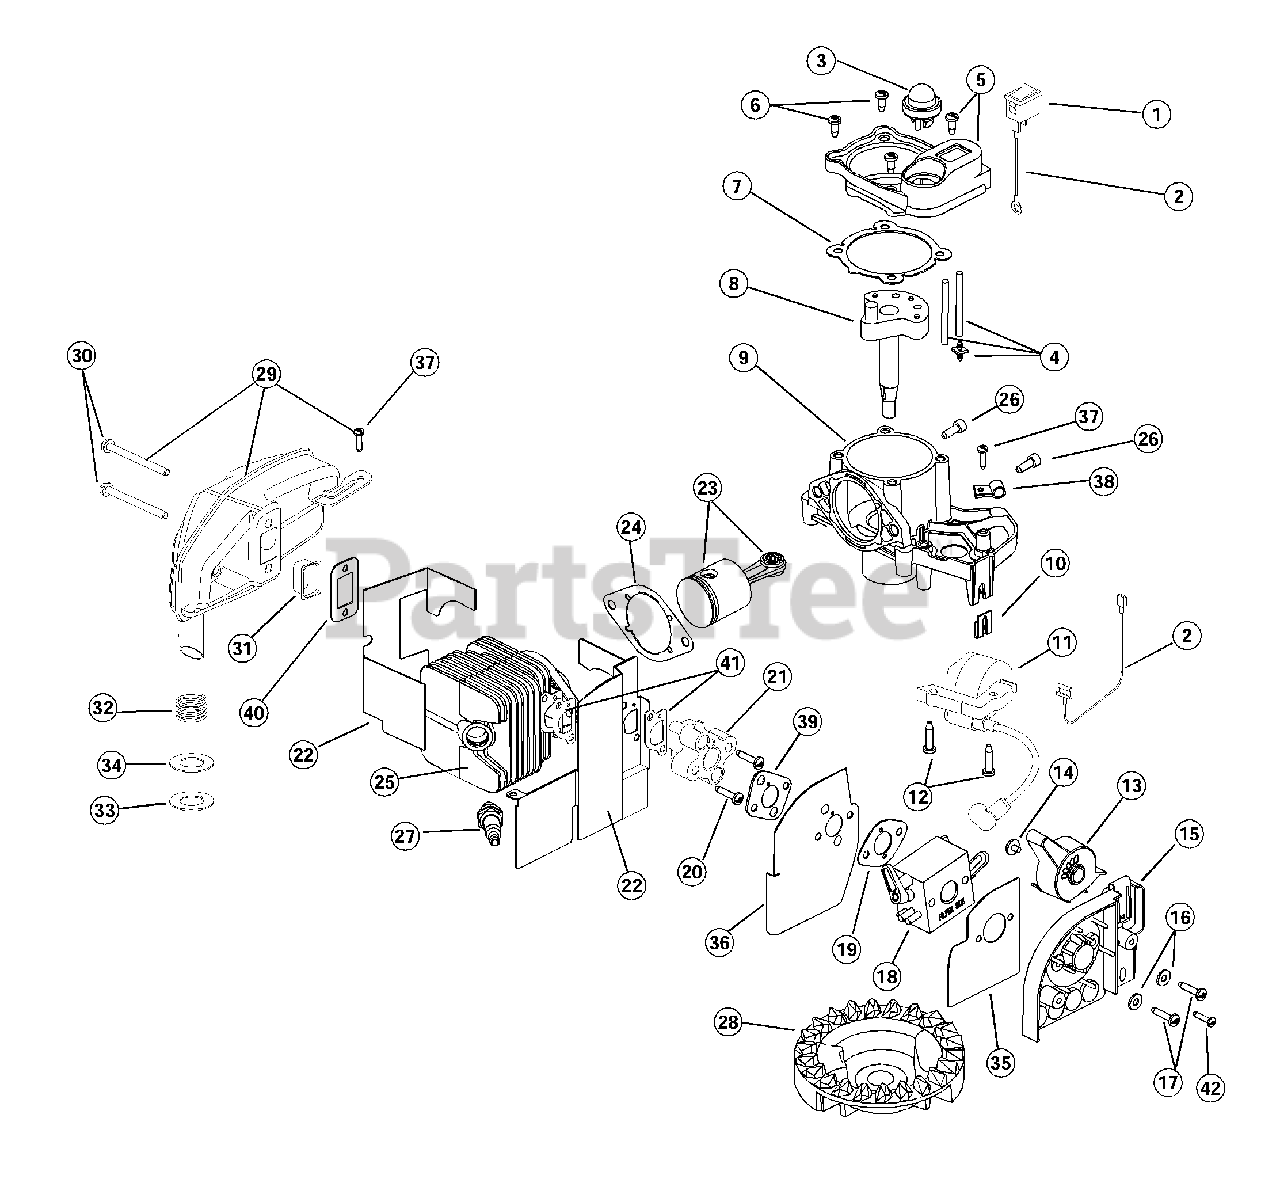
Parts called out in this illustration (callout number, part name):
1	On/Off Stop Control Switch with Wire
2	Wire Lead
3	Primer Bulb
4	Return Lines
5	Crankcase Plug
6	Crankcase Plug Screws
7	Crankcase Plug Gasket
8	Power Shaft Assembly
9	Crankcase Assembly
10	Tinnerman Nut
11	Module Assembly
12	Module Screw
13	Throttle Lever
15	Air Cleaner Base
17	Carburetor Mount Screw
18	Carburetor
19	Carburetor Gasket
20	Spacer Mounting Screw
21	Carburetor Spacer
22	Cylinder Baffle Assembly
23	Piston and Rod Assembly
24	Cylinder Gasket
25	Cylinder Assembly
26	Cylinder Bolt
27	Spark Plug
28	Flywheel
29	Muffler Assembly
30	Muffler Mounting Screw
31	Spark Arrestor Screen
32	Exhaust Tube Spring
33	Exhaust Tube Washer
34	Exhaust Tube Gasket
35	Air Filter Heat Shield
36	Carburetor Heat Shield
39	Heat Shield Gasket
40	Exhaust Gasket
41	Intake Gasket
